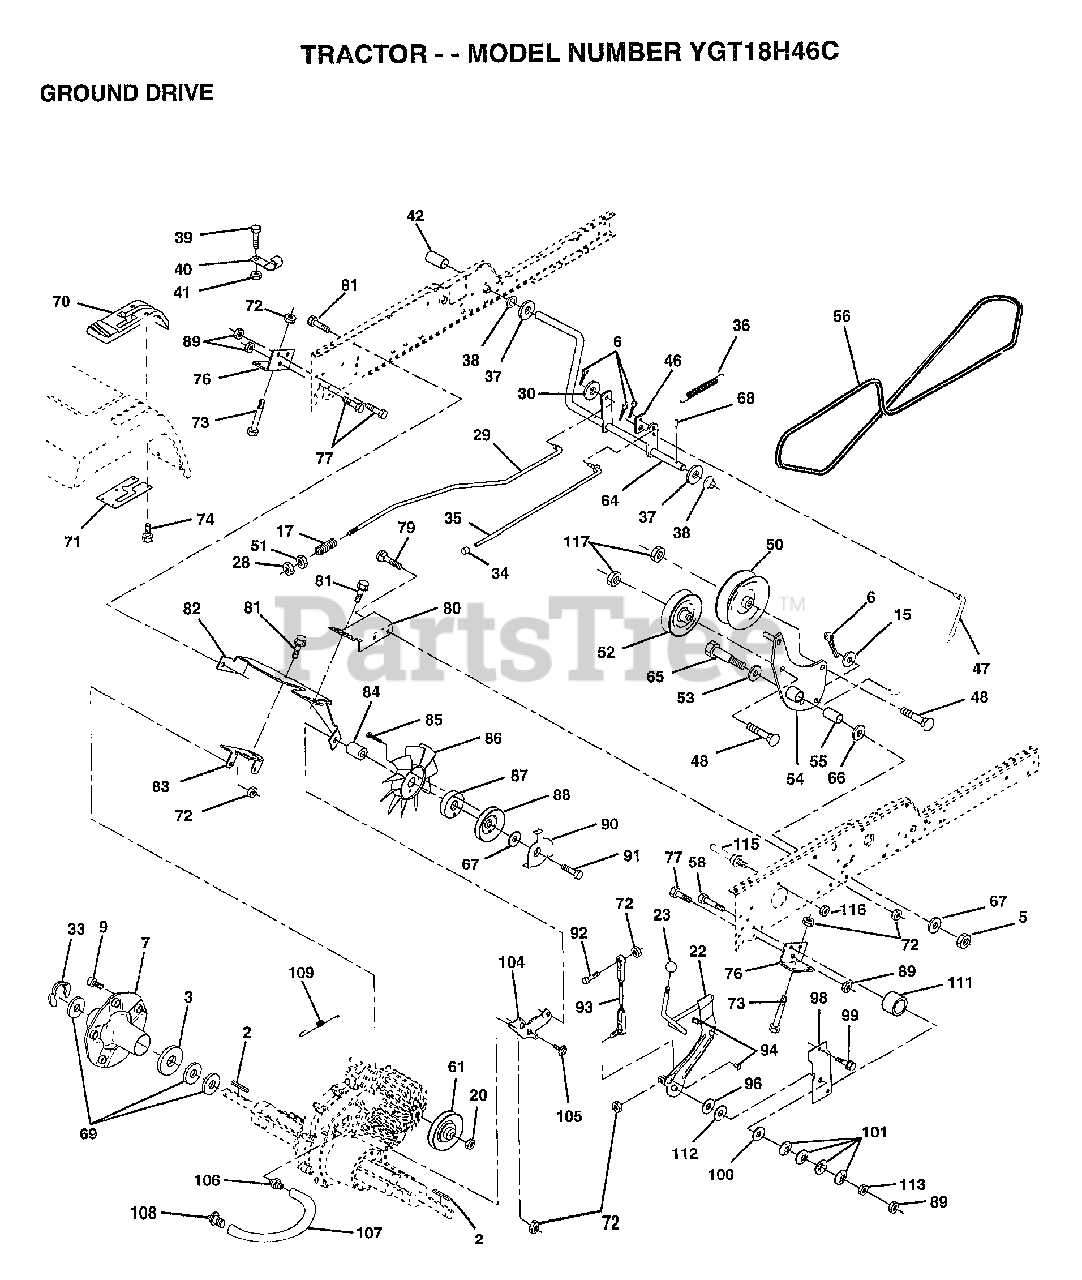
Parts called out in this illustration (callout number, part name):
2	KEY 1/4 X 2.5
3	WASHER T
6	COTTER PIN
7	HUB WHEEL ASM
9	BOLT.HUB.WHL.REAR
15	WASHER
17	SPRING ROD BRAKE
22	ARM ASM SHIFT
23	KNOB DLX BLK/BLK
28	NUT
29	ROD BRAKE
30	WASHER HYT
33	E RING HYT
34	PLUNGER CAP T
35	ROD BRAKE PART GT
36	SPRING.GRND.DRIVE
37	WASHER
38	BUSHING.NYLINER
39	SCREW
40	ACT-SWITCH T
42	"COVER,PEDAL"
46	RETAINER.SPRING
47	ROD.CLUTCH
48	BOLT.3/8-16X1.50
50	FLAT IDLER PULLEY
51	NUT
52	PULLEY.IDLER.V.GR
53	WASHER T
54	CLUTCH.ARM.ASM
55	"LY, BEARING"
56	BELT-V 84.5
58	BOLT
61	PULLEY TRANSAXLE
64	SHAFT-BRAKE/CLUTC
65	AXLE BOLT
66	WASHER.HARD.BLADE
67	WASHER
68	ROLL PIN STD
69	WASHER
70	CONSOLE.SHIFT.AUTO.YT/GT.BLACK
71	"PLATE CONSOLE,SFT"
72	NUT
73	BOLT.HEX.FLGHD.
74	SCREW HEXWSH H-L
76	BRACKET TRAN VGTH
77	BOLT
79	BOLT
80	BRACKET TORQUE RH
81	SCREW
82	BRACKET.MTG.FAN
83	STRAP TORQUE MID
84	SPACER
85	SCREW YTV
86	"FAN 7"" HYDRO"
87	ADAPTER FAN
88	PULLEY FAN
89	NUT GTV
90	KEEPER BELT
91	SCREW.HXWSH.3/8
93	LINK ASM SHIFT
94	XMAS TREE FASTNER
96	WASHER NICKEL PLT
97	BEARING THRUST
98	BRACKET SHIFT
99	SCREW LT
100	WASHER COMPRESSIN
101	WASHER-BELLVILLE
104	BRACKET IDLER
105	SCREW CRT
106	O-RING.ASM.70110
107	"LINE FUEL,HYD 15"""
108	CAP.VENT.70109
109	SPRING BRAKE
111	"SPACER-LEVER,SHIF"
112	"WASHER-NYLON,HIGH"
113	NUT
115	"KEEPER,DRIVE BELT"
116	"NUT HEX,LOCK,FLAN"
